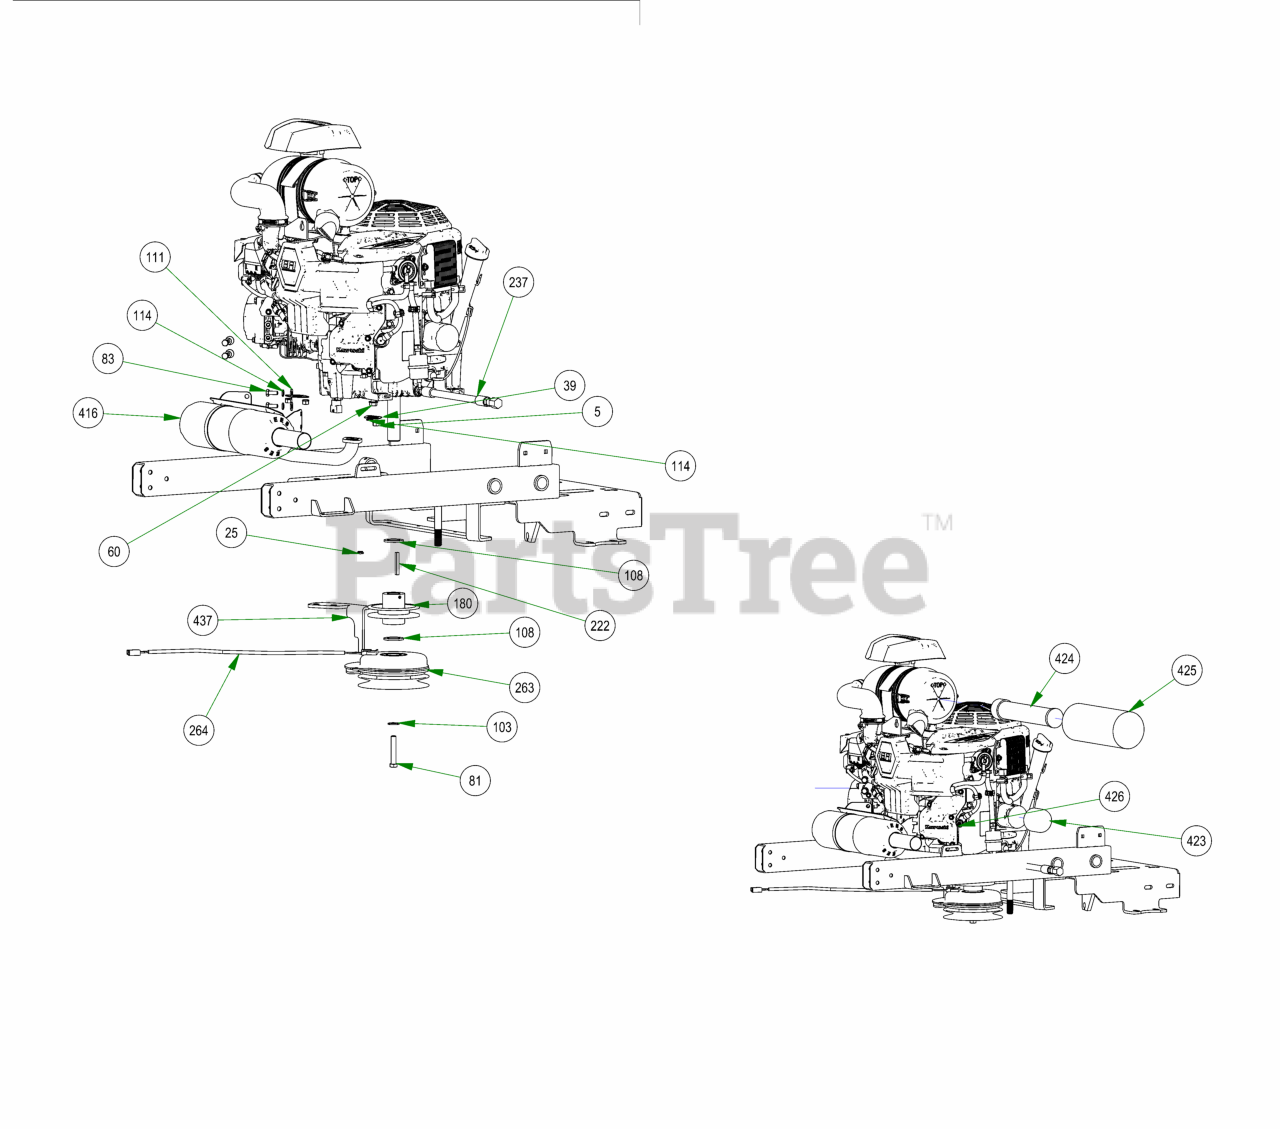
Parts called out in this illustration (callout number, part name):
5	M8-1.25 DIN 934 HEX NUT (CL.8) ZINC
25	5/16-18 NYLON INSERT JAM LOCKNUT ZINC
39	Exhaust Gasket
60	3/8-16 X 1-1/8 HEX WASHER UNSLOT SERRATED (TRI-LOB) TRS ZINC YELLOW
81	7/16-20 X 2-1/2 HEX CAP SCREW (GR.8) ZINC YELLOW
83	M8-1.25 X 20MM DIN 933 HEX TAP BOLT (CL 8.8) ZINC
103	3/8 FLAT WASHER USS (1" OD) ZINC
108	1.140 ID X 1.750 OD X .132 THICK FLAT WASHER PLAIN
111	1/4 USS FLAT WASHER (3/4 OD) ZINC
114	5/16 SPLIT LOCKWASHER ZINC
163	5/16-24 X 1/4 SOCKET SET SCREW (CUP PT) PLAIN
180	4 3/4 Motor Pulley
222	1/4 X 2 SQ MACHINERY KEY 1018 STL PLAIN
237	Kawasaki Oil Drain
240	Revolt Fuel Line Assembly
263	Clutch Assembly
264	Clutch Pigtail
265	2019 Stand On Frame
416	BBOY_MUFA_956-072922
422	Kawasaki FX820V EVO
423	Oil Filter
424	Inner Air Filter
425	Outter Air Filter
426	Spark Plug
439	Harness Adaptor for Kawasaki EFI
